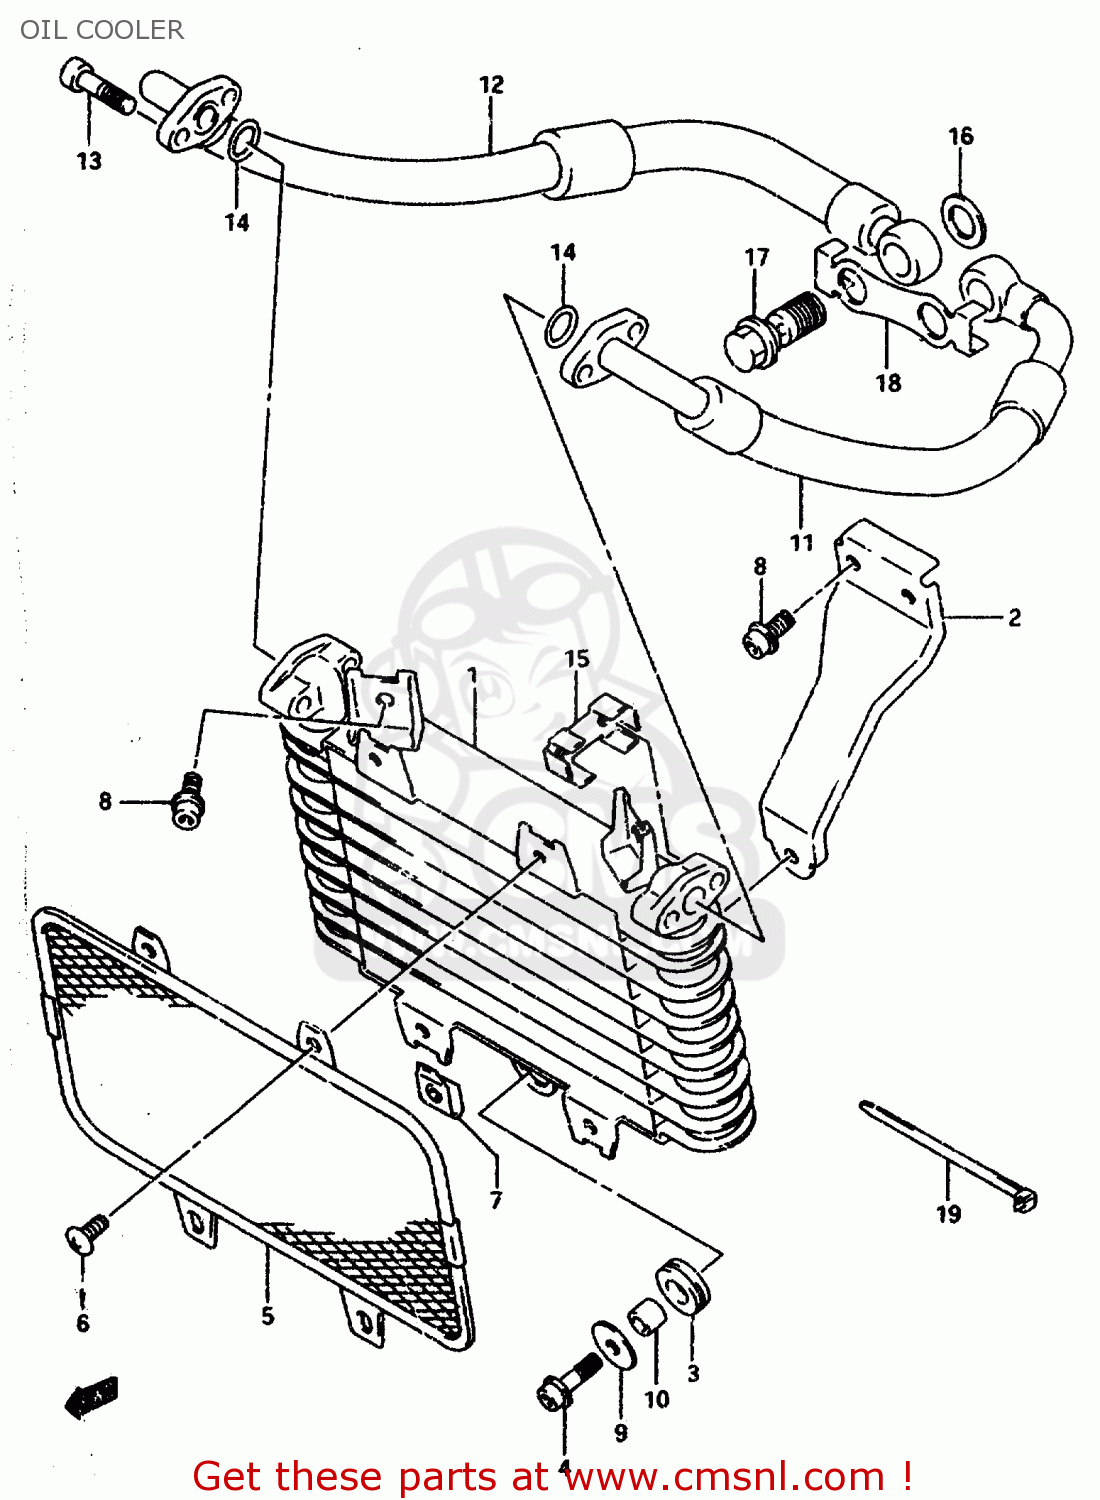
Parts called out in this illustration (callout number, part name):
1	COOLER ASSY,OIL
2	BRACKET COMP,OIL COOLER
3	CUSHION
4	BOLT
5	GUARD,OIL COOLER
6	SCREW
7	NUT
8	BOLT
9	WASHER
10	SPACER(6.5X10X10)
11	HOSE,OIL COOLER INLET
12	HOSE,OIL COOLER OUTLET
13	BOLT
14	O RING(D:2.4,ID:12.3)
15	NUT,OIL COOLER HOSE
16	GASKET(16X22X2) (NAS)
17	BOLT UNION
18	GASKET,OIL COOLER HOSE UNION
19	CLAMP
